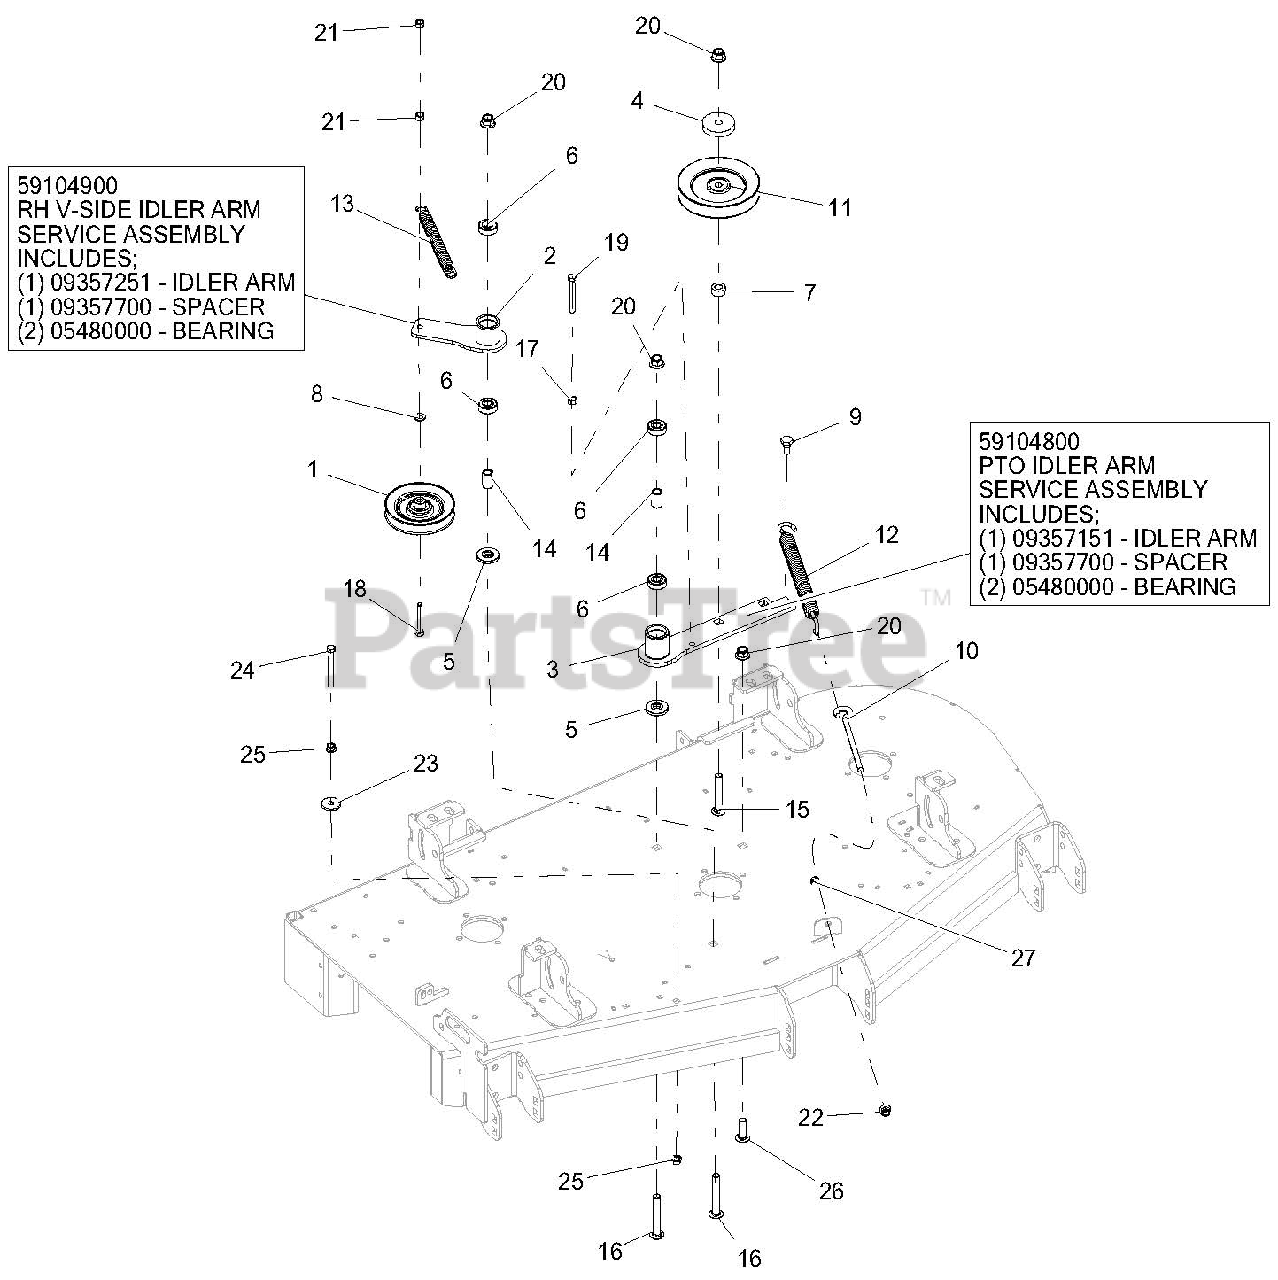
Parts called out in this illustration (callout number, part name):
1	IDLER, V-5.00" W/.69 STANDOFF
2	WLDMT, DECK RH IDLER ARM-BLACK
2	RH V-SIDE IDLER ARM SERVICE ASSEMBLY
2	IDLER ARM
2	SPACER
2	BEARING
3	WLDMT, DECK PTO IDLER ARM-BLACK
3	PTO IDLER ARM SERVICE ASSEMBLY
3	IDLER ARM
3	SPACER
3	BEARING
4	CAP, IDLER BEARING SEALING
5	SPACER, IDLER ARM
6	BRG-BALL .500X1.375X.44
7	BSHG, SPCR .502 X .997.50 PM
8	WSHR-FL-STL.406X.812X.065 YWZ
9	BLT, SHLDR EP .38-16X.30 HEX YZ
10	BOLT, .38-16X6.00 .62 DIA EYE
11	SHEAVE, .50" ID X 6.00" OD V-IDLER
12	SPRG, EXTENSION
13	SPRG, EXTENSION .120X.845X6.55 WLD
14	SPACER, .510 X .750 X 1.148
15	BLT-RDHDSQNK .50-13X3.00 G5Y
16	BLT-RDHDSQSHNK .50-13X3.25 YWZC
17	NUT-HEX .38-16 YWZC
18	BLT-HEX .38-16X2.25 GR5 YWZC
19	BLT-HEX .38-16X2.75 GR5 YWZC
20	NUT-LK-NYL-FLG .50-13 YWZC
21	NUT-LK-CTR .38-16 YWZC
22	NUT-LK-NYL-FLG .38-16 YWZC
23	WSHR-FL-STL .406X1.375X.135 YZ
24	BLT-HEX .38-16X3.00 GR5 YWZC
25	@NUT-SPNLK-FLG .375-16 YWZC
26	BLT-RDHDSQSHNK .50-13X1.50 YWZC
27	NUT, JAM .375-16 YWZC
